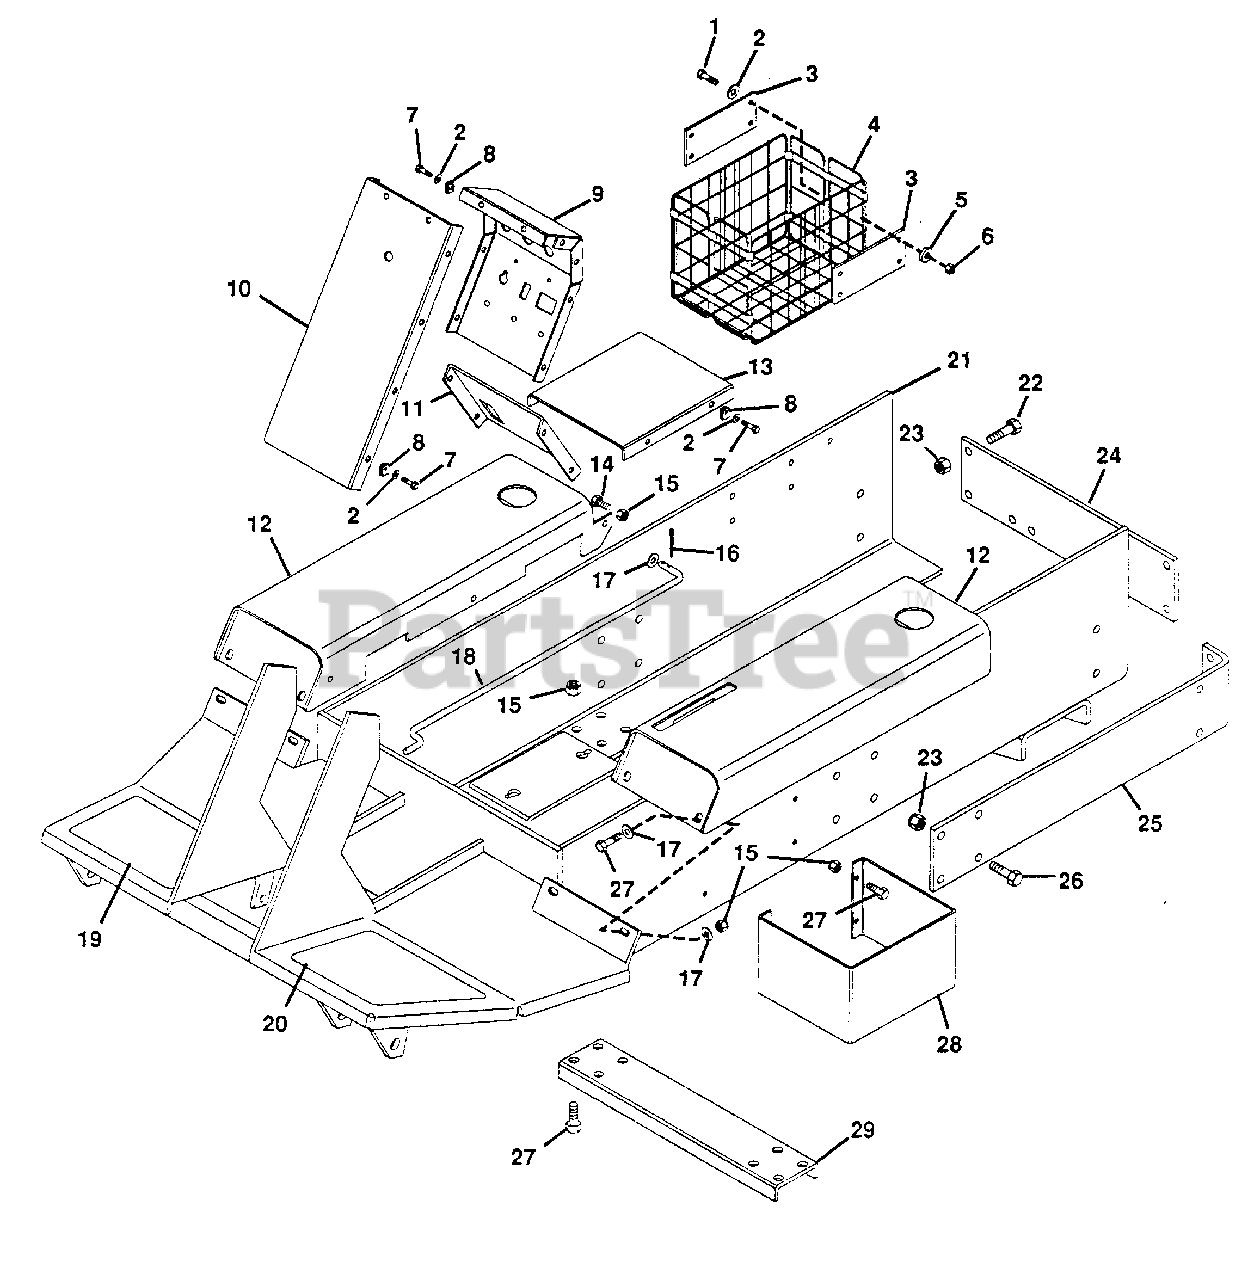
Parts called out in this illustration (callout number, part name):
1	Bolt, Hex 1/4-20x1.50
2	Washer, Flat .281x.625x.065
3	Strap, Basket
4	Basket
5	Spacer
6	Nut, Lock 1/4-20
7	Screw, Machine 1/4-20 PHD
8	Nut, Retainer
9	Panel, Silk Screen Instrument
10	Panel, Front Silk Screen
11	Panel, Brake Lock Silk Screen
12	Weldment, Fender L.H.
12	Weldment, Fender R.H.
13	Panel, Access Silk Screen
14	Bolt, Hex 3/8-16x.75
15	Nut, Lock 3/8-16
16	Pin, Cotter .094x1.00
17	Washer, Flat .406x.812x.065
18	Rod, Stay
19	Cover, R.H. Foot
20	Cover, L.H. Foot
21	Weldment, Frame
22	Bolt, Hex 1/2-13x1.50
23	Nut, Lock 1/2-13
24	Plate, Bumper
25	Bumper
26	Bolt, Hex 1/2-13x1.25
27	Bolt, Hex 3/8-16x.875
28	Bracket, Fuel Tank
29	Brace, Frame
